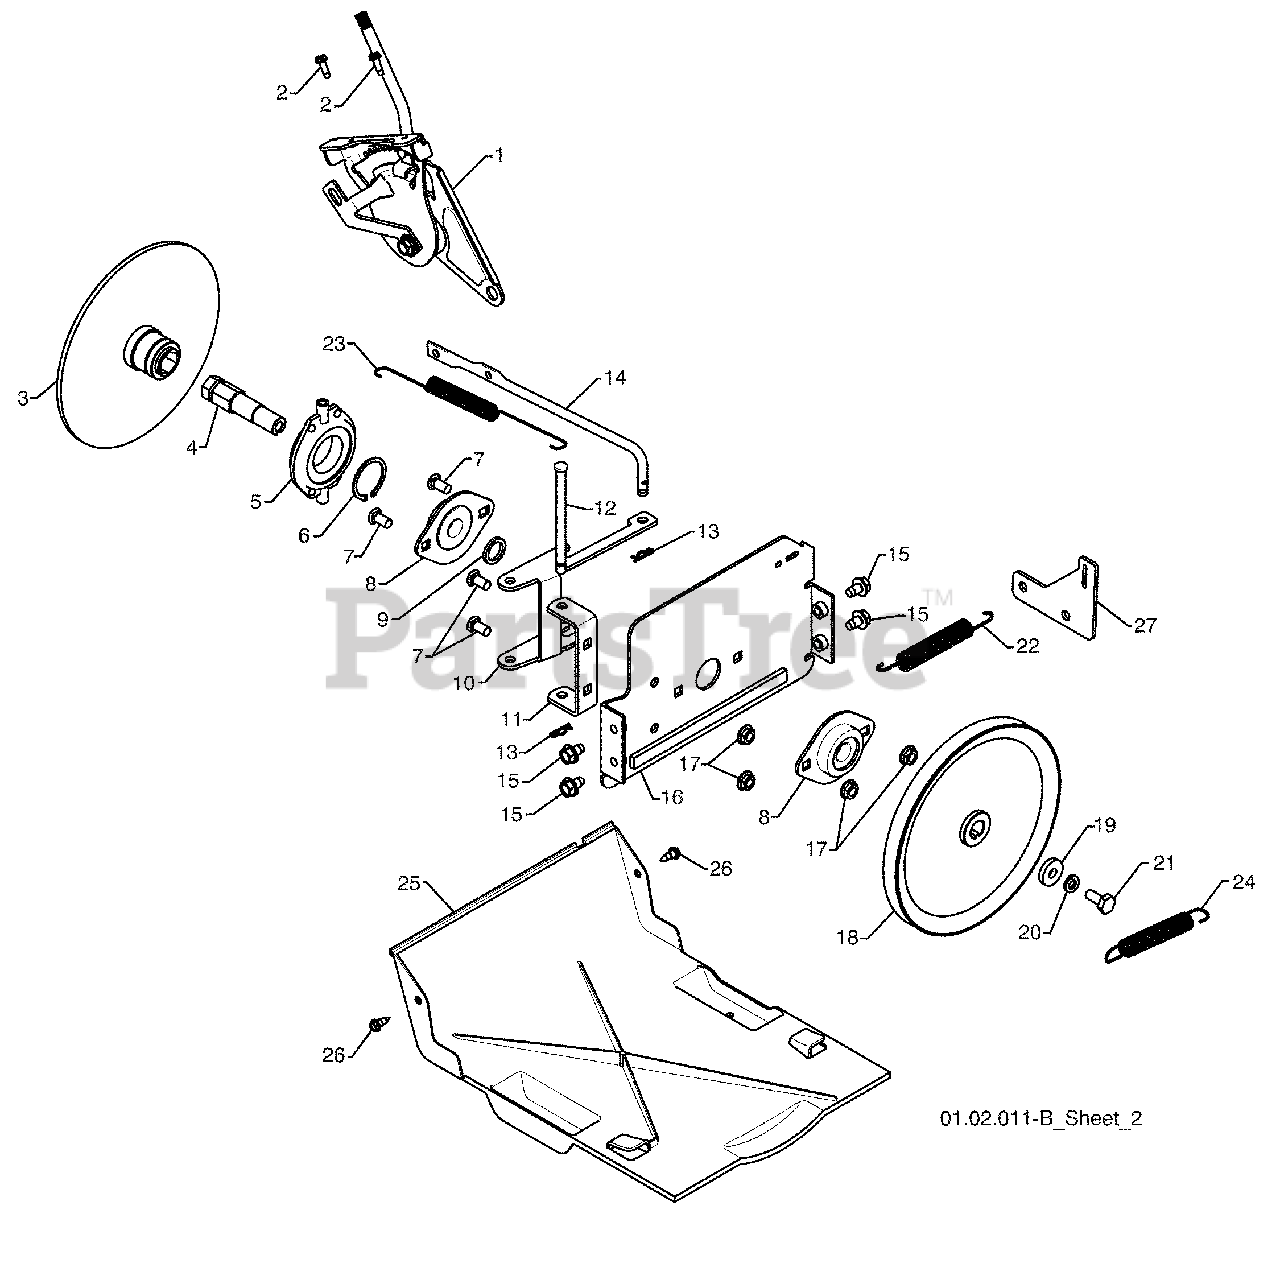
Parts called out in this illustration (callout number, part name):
1	SPEED SELECTOR HEAD ASSEMBLY
2	SCREW 10-24 X .625
3	DRIVE PLATE WELDMENT
5	TRUNNION BEARING ASSEMBLY
6	RETAINER
7	CARRIAGE BOLT 5/16-18 X .625
8	FLANGE BEARING
10	LEVER SHIFTER PLATE
11	SHIFTER SUPPORT BRACKET
14	CLUTCH ROD
15	BOLT 5/16-18 X .500
16	DRIVE MOUNT PLATE
17	NUT 5/16-18
18	TRACTION PULLEY
20	LOCKWASHER 5/16
21	SCREW 5/16-18 X .750
22	TRACTION SPRING
23	RETURN SPRING
24	BRAKE SPRING
25	BOTTOM PAN
26	SCREW 10-24 X .625
27	TRACTION SPRING BRACKET
